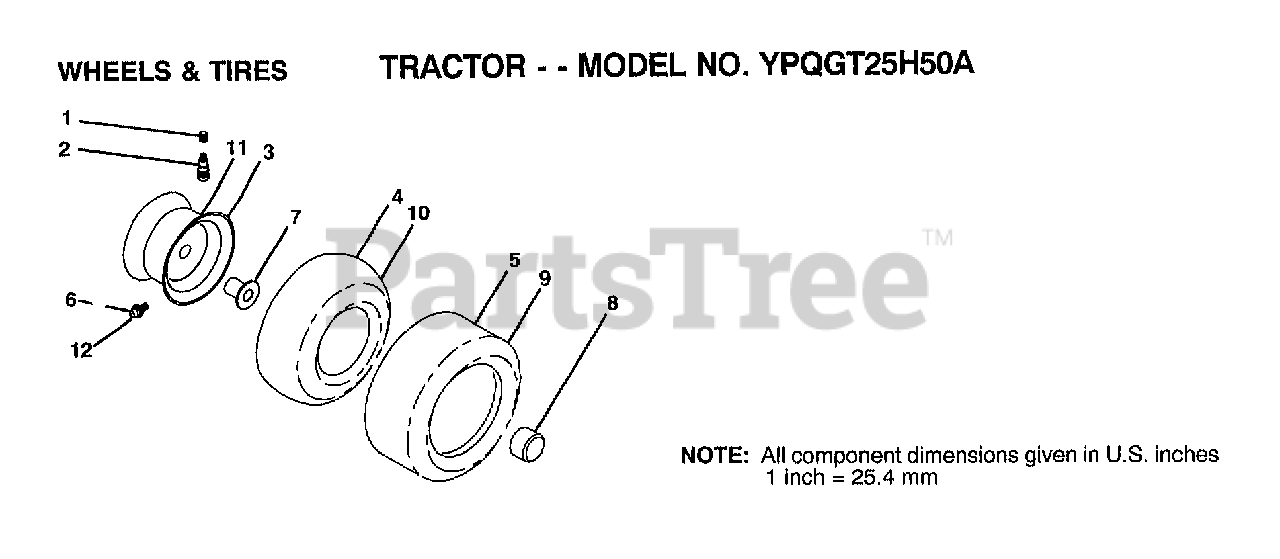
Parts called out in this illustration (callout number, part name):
1	VALVE CAP
2	VALVE STEM LT
3	"RIM ASM 8"" FRT"
4	TUBE.16X6.5/7.5-8
6	FITTING LT
7	"FLANGE, BEARING"
8	HUB CAP
10	TUBE.23X8/10-12
11	"RIM ASM 12"" REAR"
12	ZERK FITTING M
